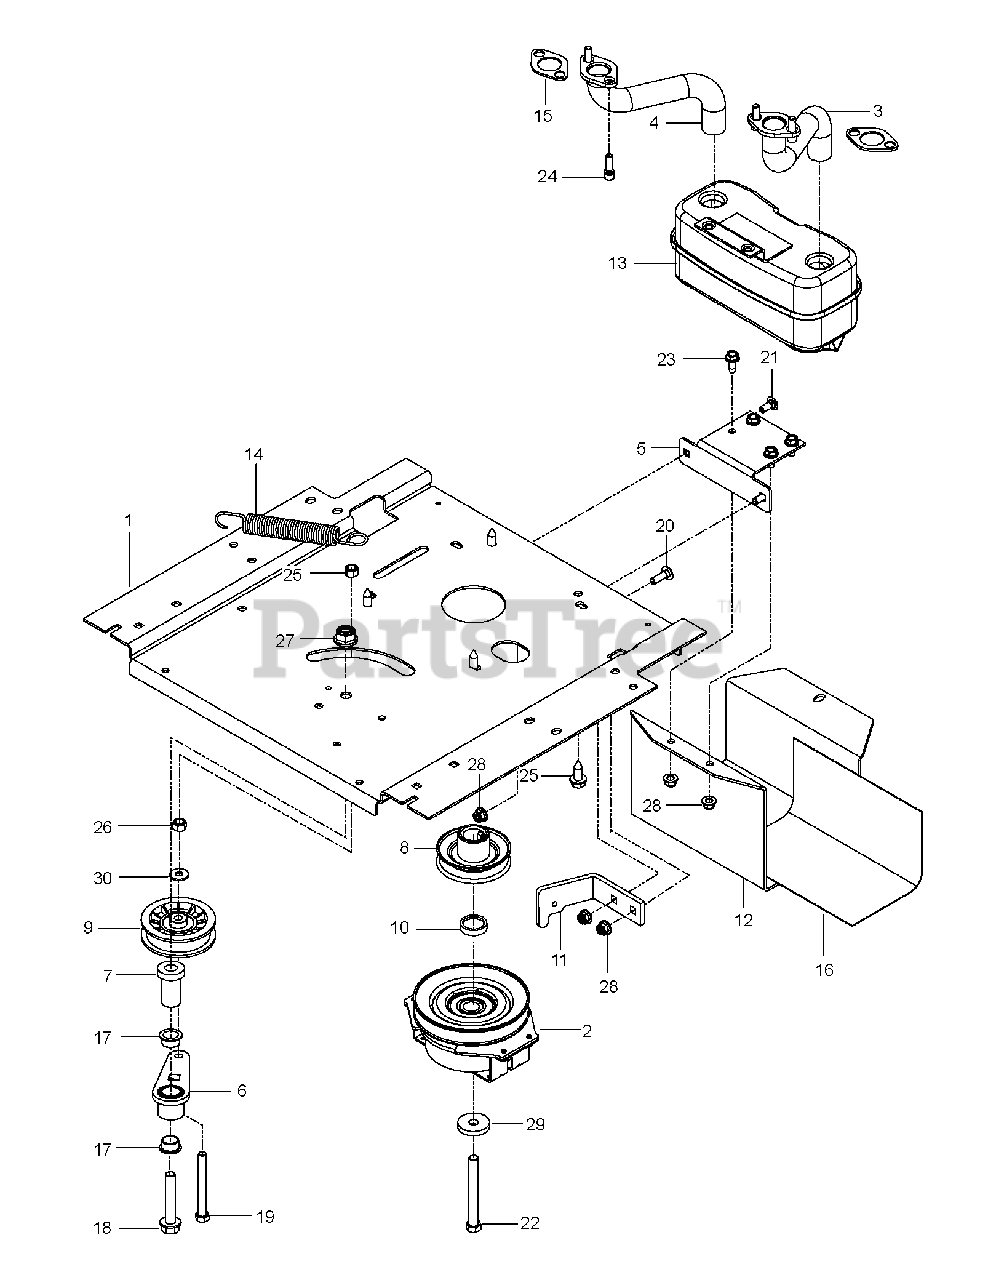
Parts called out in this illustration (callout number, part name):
1	PLATE.ENGINE.PNT.23"FRAME.EDIP
2	CLUTCH.OGURA.5.0PD.GT1.5A-EH07
3	EXHAUST.TUBE.RH.B&S.TWIN.INTEK
4	EXHAUST.TUBE.LH.BS/TWIN
5	BRACKET MUFFLER MS431BLK
6	ARM IDLER
7	SPINDLE.IDLER
8	PULLEY.ENGINE
9	PULLEY, IDLER RAKE & ZTR
10	SPACER.SPACER.625 W/OGURA.LCC
11	CLUTCH.STOP.OGURA LCC.BLACK
12	GUARD.MUFFLER.WO.TOW.HITCHX431
13	MUFFLER ASM TWIN
14	SPRING, DECK DRIVE
15	GASKET.MUFFLER
16	HEAT SHIELD
17	BEARING.FLANGED.PLASTIC.3/4ID
18	BOLT.FLANGE.1/2-13 X 2.75.GRD5
19	HCS 3/8-16X3-1/2 TAPBLT GR5 ZD
21	BOLT 5/16-18 X3/4 ZN/YEL GR 5
22	CLUTCH BOLT7/16-20X2.5 GR524HR
23	SCREW
24	SCREW.SOCKET.HEAD.5/16-18
25	SCREW 3/8-16X1
26	NUT 3/8-16 NYLOC
27	NUT, 1/2-13 HEX FLG NYLOC ZD
28	5/16-18 NYLOC FLANGE NUT
30	WASHER
